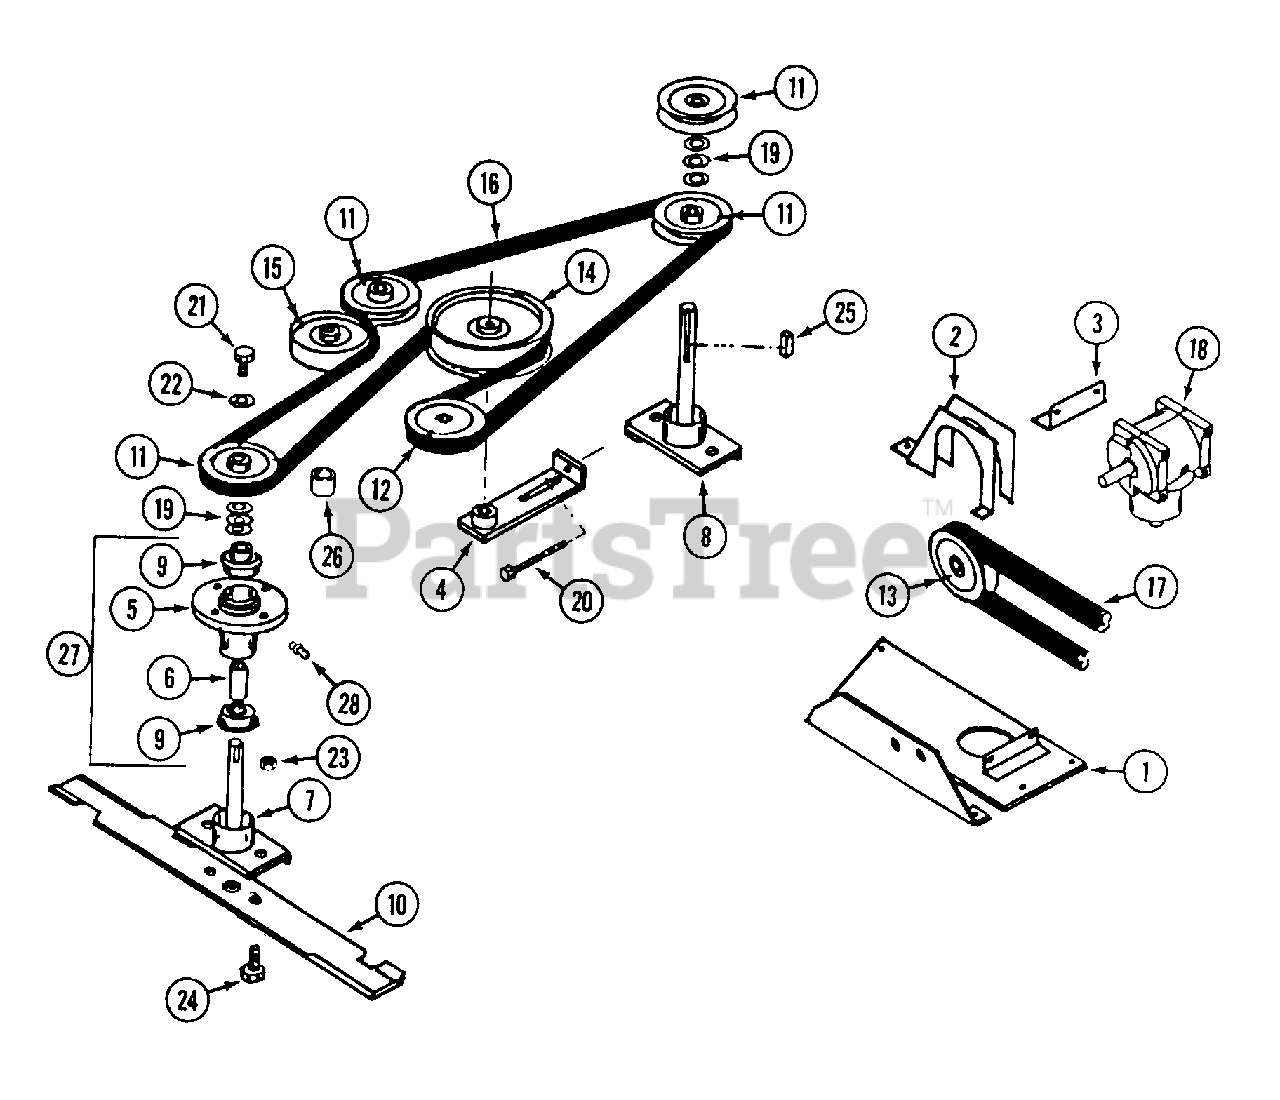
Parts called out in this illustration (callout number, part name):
1	MOUNT - gear box
2	GUARD - belt
3	ANGLE - gear box mount
4	TIGHTENER - belt
5	HOUSING - spindle
6	SPACER - spindle
7	SHAFT - spindle, short
8	SHAFT - spindle, long
9	BEARING - spindle
9	BEARING - spindle 7/8"
11	PULLEY - spindle
12	PULLEY - gear box output
13	PULLEY - gear box input
14	PULLEY - idler, large
15	PULLEY - idler, small
18	GEAR BOX - angle drive
19	WASHER - spacer
20	BOLT - 1/4" - 20 x 4"
21	BOLT - 3/8" - 24 x 1-1 /4"
22	WASHER - spindle
23	NUT - 3/8" - 16 lock
24	BOLT - 3/8" - 16 x 1"
25	KEY - 3/16" x 3/16" x 1"
26	SPACER - idler pulley
27	HOUSING ASSEMBLY - spindle
28	FITTING - grease 1/4" - 28
